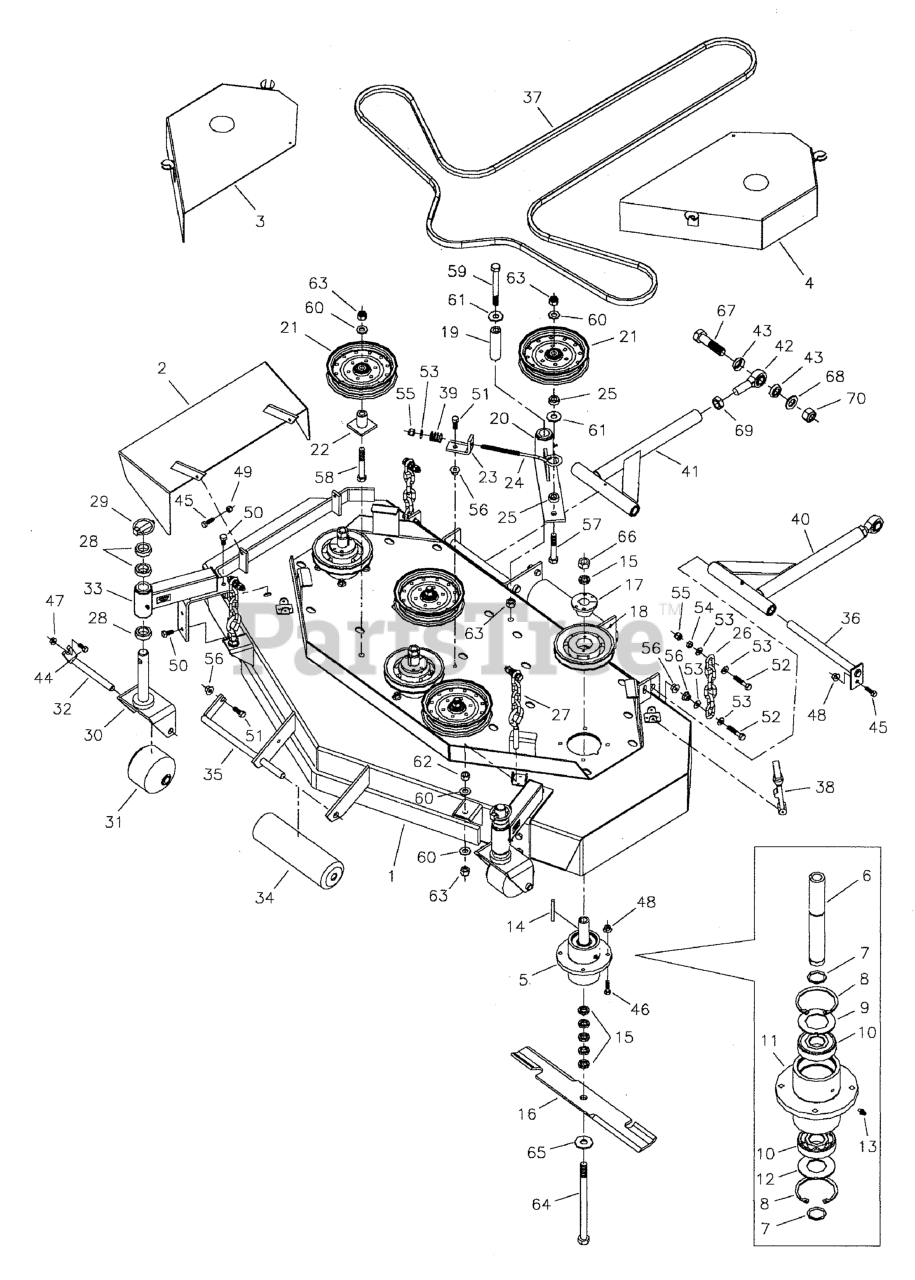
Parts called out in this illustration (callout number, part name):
1	PCZ52 MOWER HOUSING
2	CHUTE, DISCHARGE WELDMENT
3	GUARD, Deck, Right
4	GUARD, Deck, Left
5	SPINDLE ASSEMBLY, Complete
6	SPINDLE SHAFT
7	SNAP RING, External
8	SNAP RING, Internal
9	SPINDLE WASHER, Top
10	BEARING
11	SPINDLE HOUSING
12	SPINDLE WASHER, Bottom
13	GREASE FITTING
14	KEY, 1/4 SQ. X 2-1/2
15	SPACER, .63 x 1.06 x .23
16	MOWER BLADE, 18"
17	BUSHING, Tapered Hub
18	PULLEY, Spindle
19	SPACER, .52 x 1.00 x 3.50
20	IDLER ARM ASSEMBLY
20	BUSHING, FLANGE
20	GREASE FITTING
20	ASSM, IDLER ARM
22	IDLER PULLEY MOUNT
23	SPRING ANCHOR
24	EYEBOLT, 3/8" x 8"
25	SPACER, .52 x 1.00 x .44
26	CHAIN, 6 LINKS
27	HANGER, FRONT DECK - 4 LINK, 5.5" EB
28	SPACER, 1.02 x 1.56 x .50
29	PIN, Lynch
30	CASTER YOKE
31	ROLLER, Caster
32	CASTER ROLLER PIN
33	ARM, DECK CASTER ASSEMBLY
33	DECAL, Grease Daily
33	GREASE FITTING
33	BUSHING, FLANGE
33	CAP, Plastic
34	ROLLER
37	BELT, 5V, 150.90"EL, ARAMID, WRPD, RC
38	RUBBER LATCH
39	SPRING, Compression
40	52" DECK PUSHER BAR-LH
41	52" DECK PUSHER BAR-RH
42	BALL JOINT, 3/4-16 Male
43	ROD END SEAL
44	BOLT, 5/16-18 X 3/4 GD5
45	BOLT, 5/16-18 X 1 GD5 YZ
46	BOLT, 5/16-18 x 1-1/4
47	NUT, 5/16-18 HEX SERRATED FLANGE (SMALL)
48	NUT, 5/16-18 HEX SERRATED FLANGE (LARGE)
49	NUT, 5/16-18 Hex Nylon Lock
50	BOLT, 3/8-16 X 3/4" GD5 CZ
51	BOLT, 3/8-16 X 1" GD5 CZ
52	BOLT, 3/8-16 X 1-3/4" GD5 CZ
53	WASHER, 3/8 SAE
54	NUT, 3/8-16 HEX JAM
55	NUT, 3/8-16 HEX NYLON LOCK
56	NUT, 3/8-16 Hex Serrated Flange
57	BOLT, 1/2-13 X 3" GD5 CZ
58	BOLT, 1/2-13 X 3-1/2, HEX HD, GD5, CZ (SV)
59	BOLT, 1/2-13 x 4-1/2
60	WASHER, 1/2 SAE
61	WASHER, 1/2" USS
62	NUT, 1/2-13 Hex
63	NUT, 1/2-13 HEX NYLON LOCK
64	BOLT, 5/8-11 x 9-1/2
65	WASHER, 5/8" USS
66	NUT, 5/8-11 Hex
67	BOLT, 3/4-16 x 3
68	WASHER, 3/4 SAE
69	NUT, 3/4-16 Hex Jam
70	NUT, 3/4-16 Hex Nylon Lock
